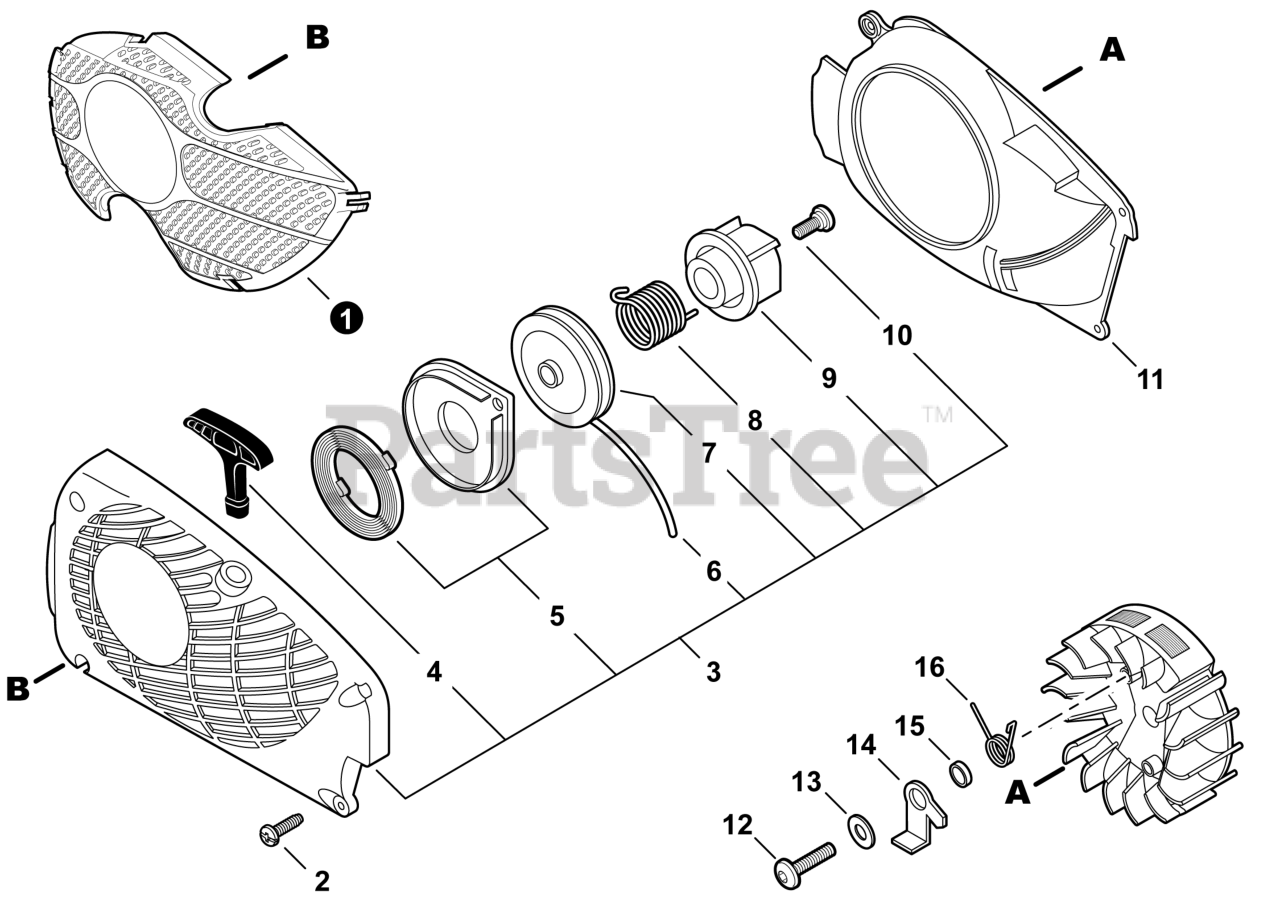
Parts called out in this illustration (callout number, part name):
1	SHIELD, DEBRIS
2	SCREW 4×16
3	STARTER ASSY, RECOIL
4	GRIP, STARTER
5	SPRING KIT, RECOIL
6	ROPE, STARTER 3.5×900
7	REEL, ROPE
8	SPRING, TORSION
9	PAWL CATCHER
10	SCREW
11	COVER, FAN
12	BOLT 5×14
13	WASHER 5.5×12×0.8
15	SPACER 5.2×8×2.1
16	SPRING, TORSION
